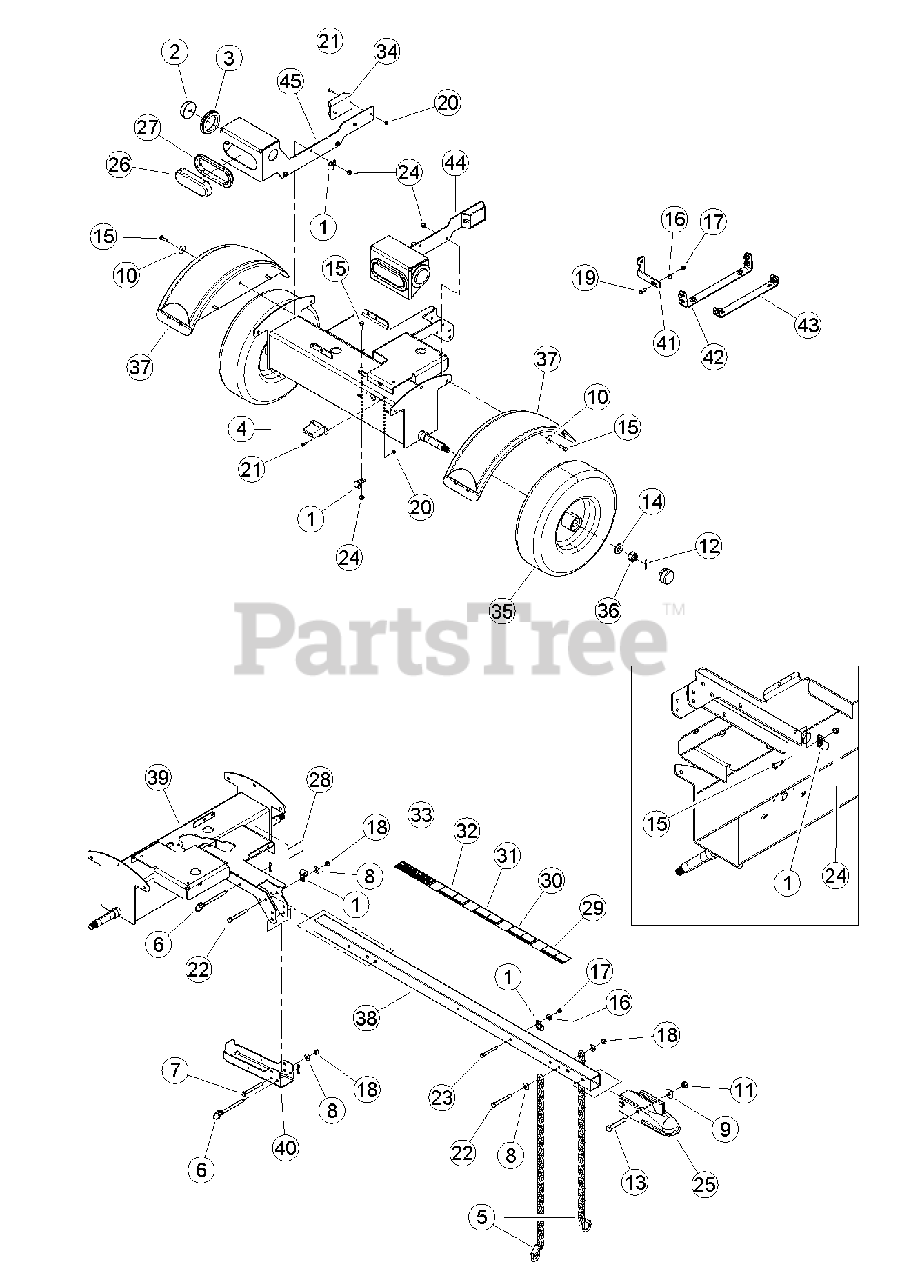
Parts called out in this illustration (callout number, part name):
1	CLAMP, 9/16 COATED
2	LIGHT, RED CLEARANCE
3	GROMMET, CLEARANCE LIGHT
4	LIGHT, LICENSE PLATE
5	CHAIN, SAFETY 5000 LB W/ LATCH
6	PIN, 3/8 HITCH
7	BOLT, 3/8 X 3-1/2 HEX HD GR5 ZP
8	WASHER, 3/8 FLAT ZP
9	WASHER, 1/2 FLAT ZP
10	WASHER, 5/16 FENDER ZP
11	NUT, 1/2 CENTERLOCK GRB ZP
12	PIN, 5/32 X 1-1/4 COTTER ZP
13	BOLT, 1/2 X 3 HEX HD GR5 ZP
14	WASHER, 3/4 SAE FLAT ZP
15	BOLT, 5/16 X 1 HEX HD GR5 NC ZP
16	WASHER, 5/16 FLAT ZP
17	NUT, 5/16 NE NYLOCK ZP
18	NUT, 3/8 NE NYLOCK ZP
19	BOLT, 5/16 X 7/8 HEX NC GR5 ZP
20	NUT, 10/24 NYLOCK TYPE NM ZP
21	MACH. SCREW, #10-24 X 3/4 PAN HD PH ZP
22	BOLT, 3/8 X 3-1/4 HEX HD GR5 ZP
23	BOLT, 5/16 X 2-3/4 HEX HD GR5
24	NUT, 5/16 FLANGE TOPLOCK
25	TRAILER HITCH COUPLER
26	TAIL LIGHT, OVAL LED
27	GROMMET, OVAL TAIL LIGHT
28	DECAL, 4.80-8 LOAD RATING (LOG SPLITTER)
29	DECAL, SAFETY CHAINS
30	DECAL, TRAILER ELECTRICAL
31	DECAL, PINTLE SAFE COUPLING
32	DECAL, CHECK WHEELS
33	DECAL, SAFE TOWING SPEED
34	LIGHT, AMBER SIDE MARKER
35	ASSEMBLY, TIRE 4.8-8
36	NUT, SLOTTED 3/4-16 GRADE 2
37	FENDER, BLACK PLASTIC DRILLED
38	TUBING, HITCH POLE
39	WELDMENT, SC 3" TRAILER
40	STAND, JACK
41	BRACKET, CORNER
42	BRACKET, ENGINE BASE
43	BRACKET, ENGINE BASE
44	BRACKET, RIGHT TAIL LIGHT
45	BRACKET, LEFT TAIL LIGHT
